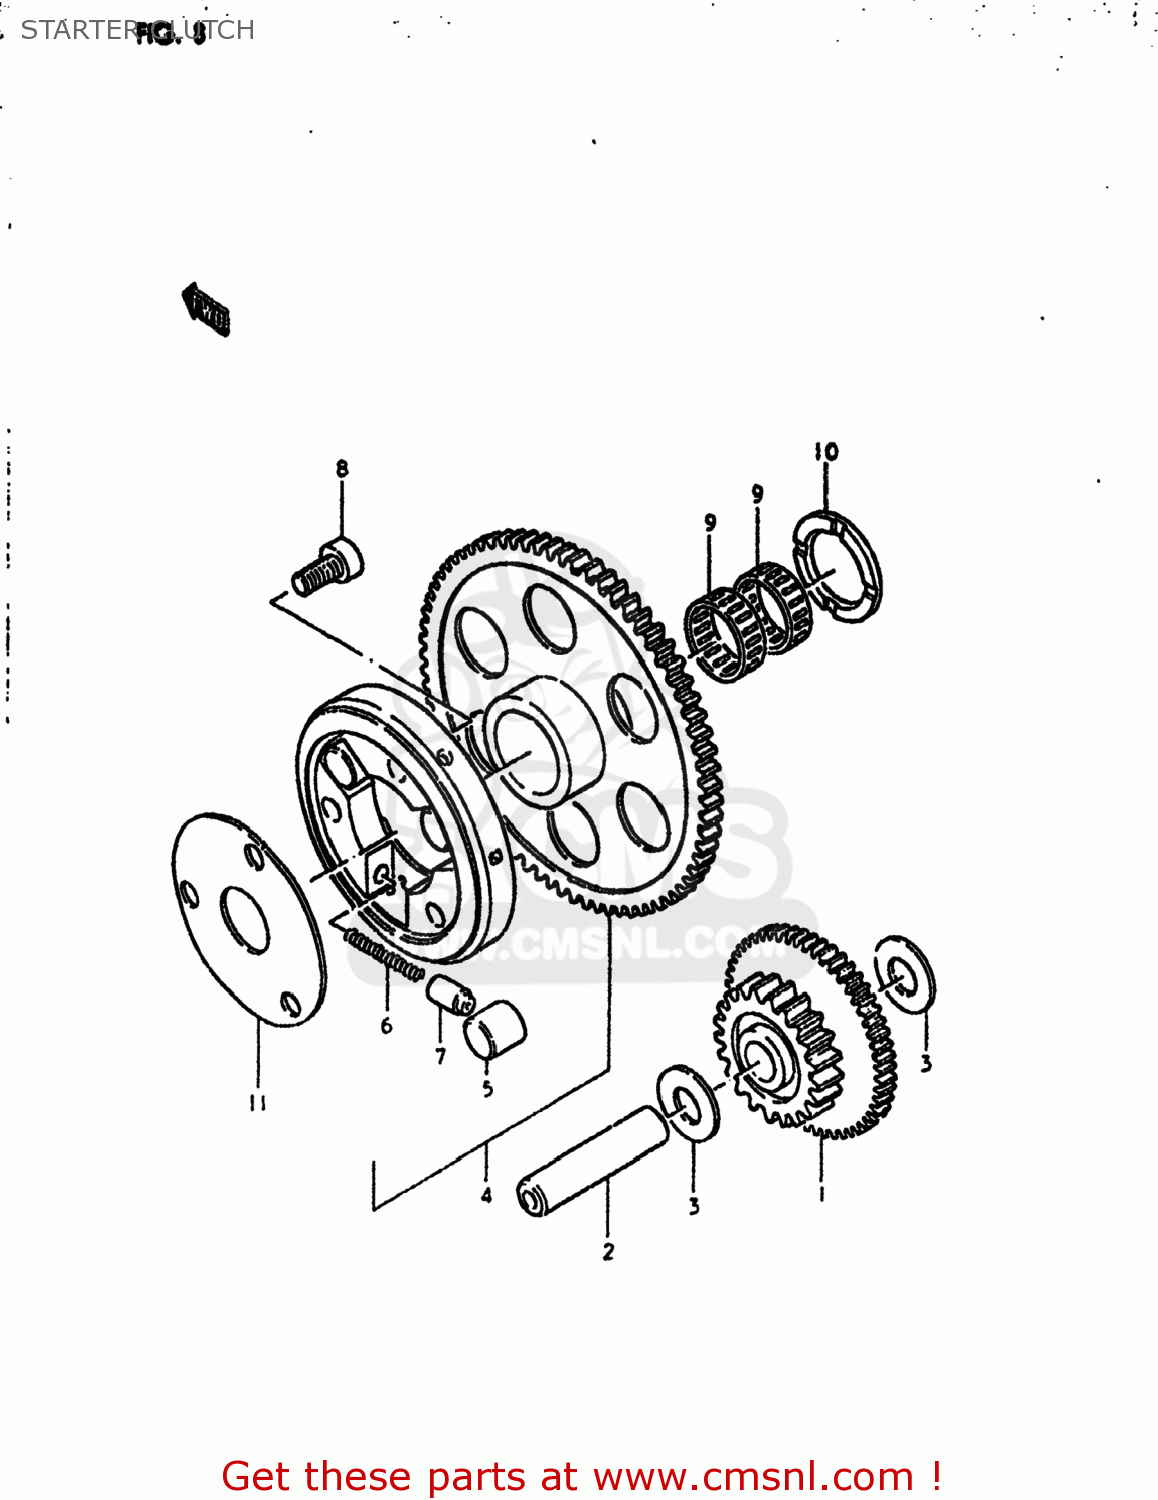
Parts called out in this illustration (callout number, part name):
1	GEAR,STARTER IDLE
2	PIN(7.4X13X56)
3	WASHER(13.3X25X0.85)
4	CLUTCH SET,STARTER
5	ROLLER(15X13)
6	SPRING
7	PIECE,PUSH
8	BOLT
9	BEARING
10	WASHER(25X38X2.5)
11	SHIM,STARTER CLUTCH HUB
